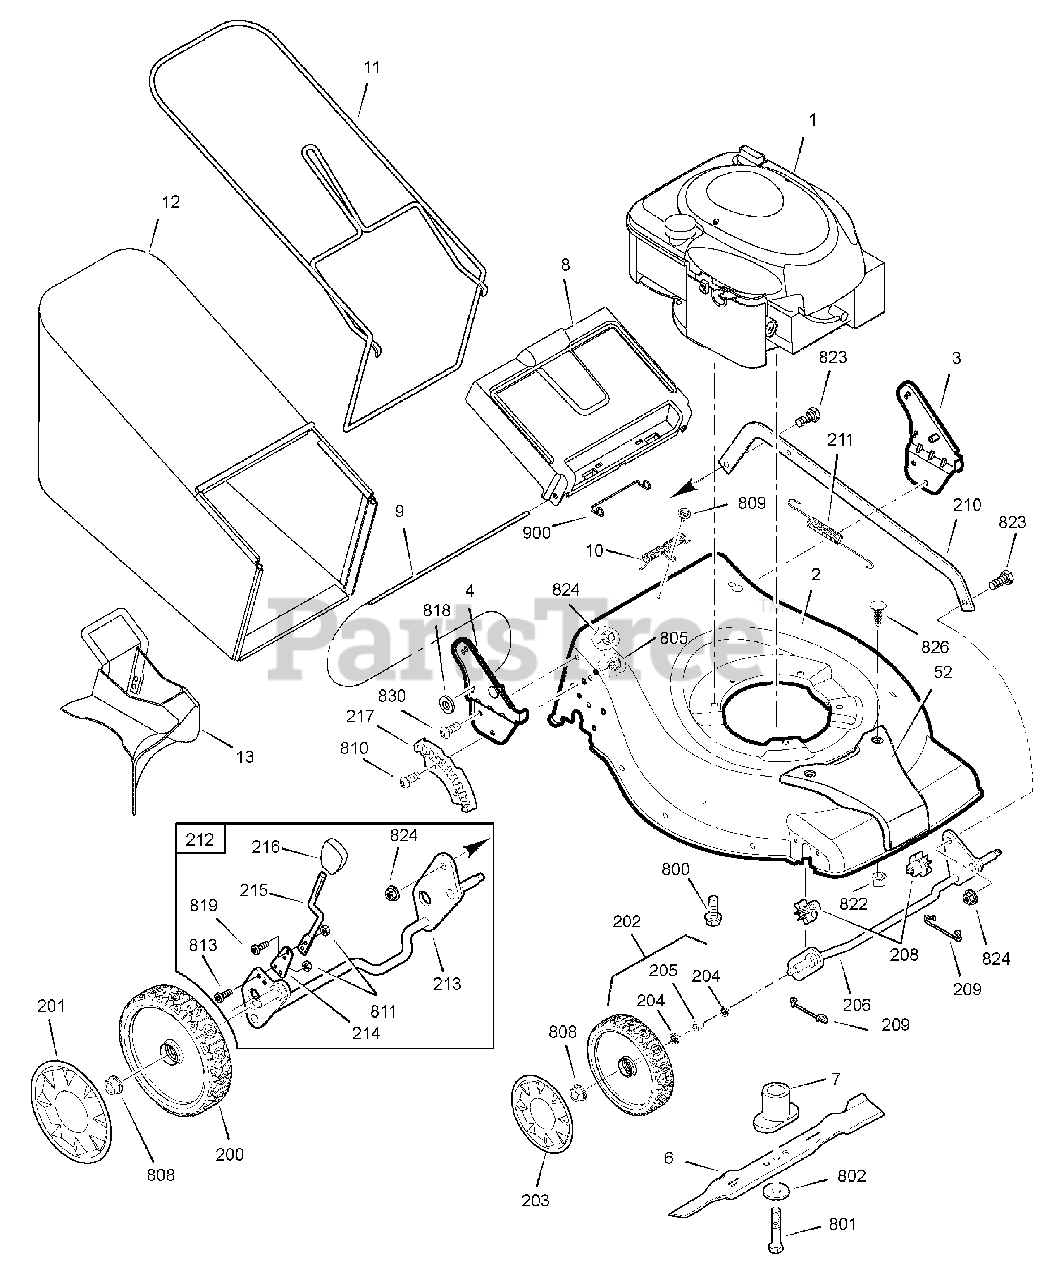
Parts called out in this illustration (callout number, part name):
1	* ENGINE, B&S 675 Series, EU
2	MOWER HOUSING
3	BRACKET ASSEMBLY, Left Handle
4	BRACKET ASSEMBLY, Right Handle
6	BLADE, 16"
7	BLADE ADAPTER ASSEMBLY
8	DOOR, Rear
9	ROD, Rear Door
10	SPRING, Torsion Rear Door
11	FRAME ASSEMBLY
12	BAG ASSEMBLY
13	MULCH PLUG
52	HOUSING COVER, Front
200	WHEEL, Rear
201	HUBCAP, Rear
202	WHEEL, Front, Complete
203	HUBCAP, Front
204	WHEEL BEARING (Not Available)
205	SPACER (Not Available)
206	CROSSBAR ASSEMBLY, Front
208	BUSHING, Front Crossbar
209	SPRING, Clip Crossbar
210	LINK, Single Lever
211	SPRING, Extension
212	CROSSBAR ASSEMBLY, Rear (Not Available)
213	REAR CROSSBAR
214	SPRING, Adjuster
215	LEVER, Height Adjustment
216	KNOB, Adjuster
217	BRACKET, Height Adjuster
800	SCREW, Hex Head, 3/8-16 x 1
801	BOLT, Blade, 3/8-24 x 2
802	WASHER, Belleville
805	NUT, Nylock, M8 x 1-1/4
808	NUT, Flange, 3/8-16
809	SCREW, Self Tap, #10-16 x 1/2
810	BOLT, Hex Key Head
811	NUT, Nylock
813	SCREW, Torx Head, M5 x .8 x 14mm
818	NUT, Speed
819	SCREW, Torx Head, M5 x .8 x 12.5mm
822	NUT, Hex, 1/4-20
823	BOLT, Shoulder, 5/16-18 x 1
824	Nut, Flange, 5/16-18
826	SCREW, 1/4-20 x 7/8
830	SCREW , 5/16-18 x 3/4
900	SPRING CLIP, Rear Door
1000	DECAL KIT
1001	MANUAL KIT
